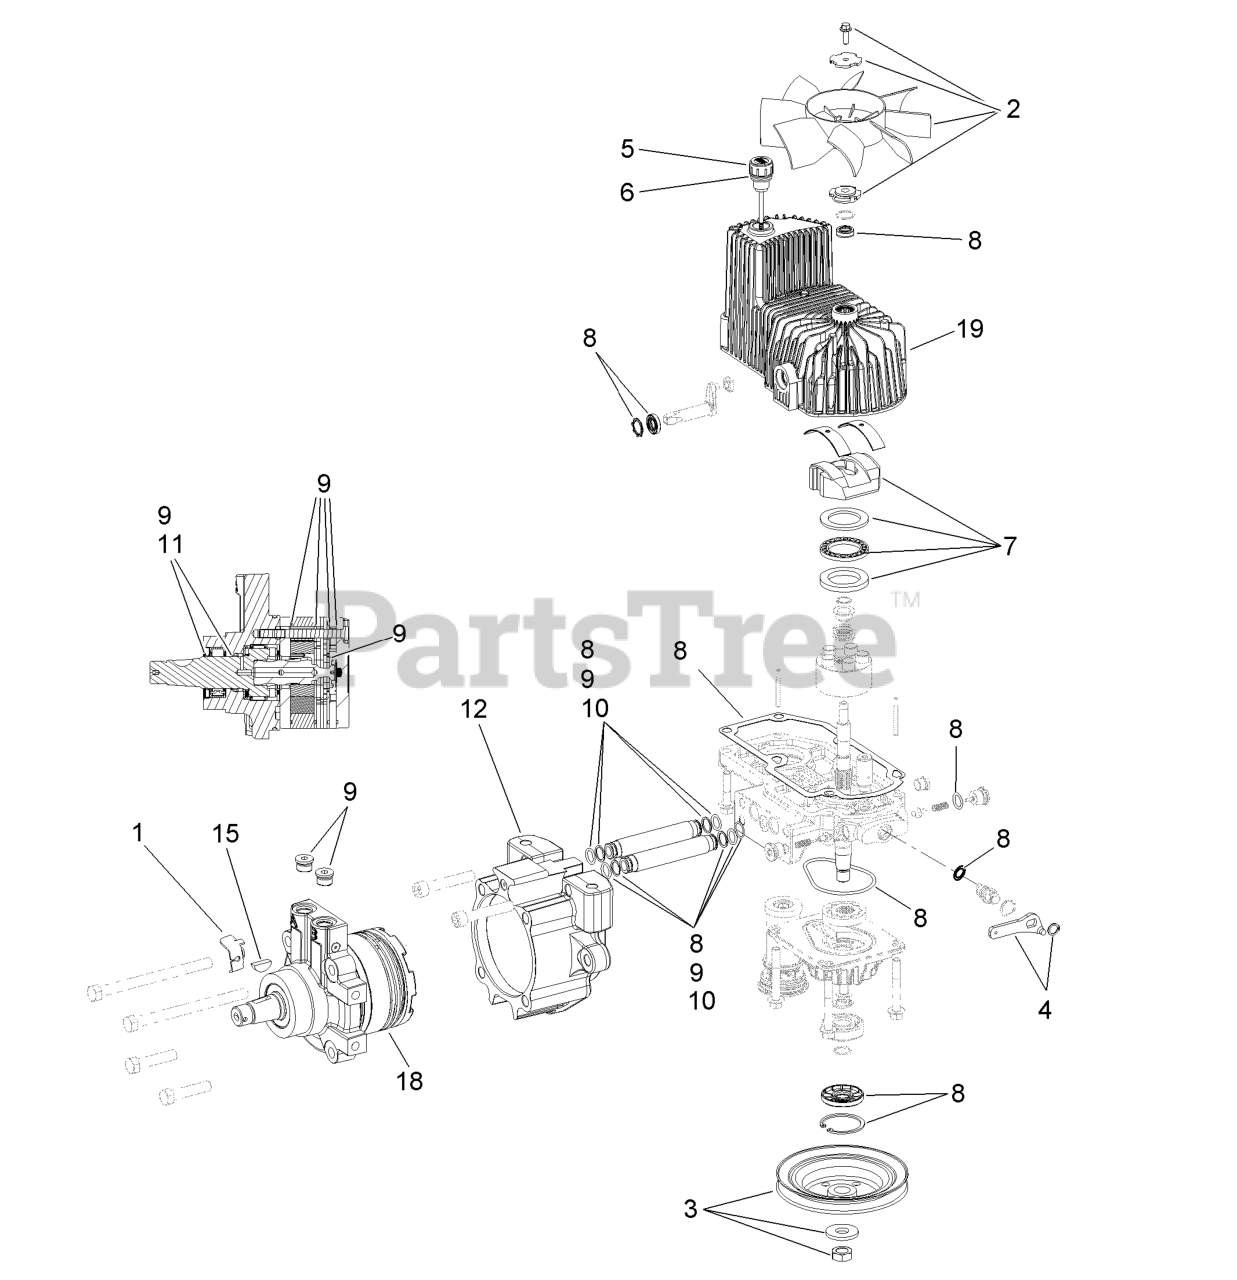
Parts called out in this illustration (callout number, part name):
1	BRACKET-ANCHOR, CABLE
2	FAN KIT
3	PULLEY KIT
4	HANDLE-BYPASS VALVE, HYDRO
5	DIPSTICK-HYDRO W/GASKET
6	GASKET-DIPSTICK, HYDRO
7	SWASH BLOCK KIT
8	PUMP SEAL KIT
9	MOTOR SEAL KIT
10	TUBE SEAL KIT
11	OUTPUT SHAFT SEAL KIT
15	KEY-WOODRUFF
19	HOUSING-HYDRO, RH
